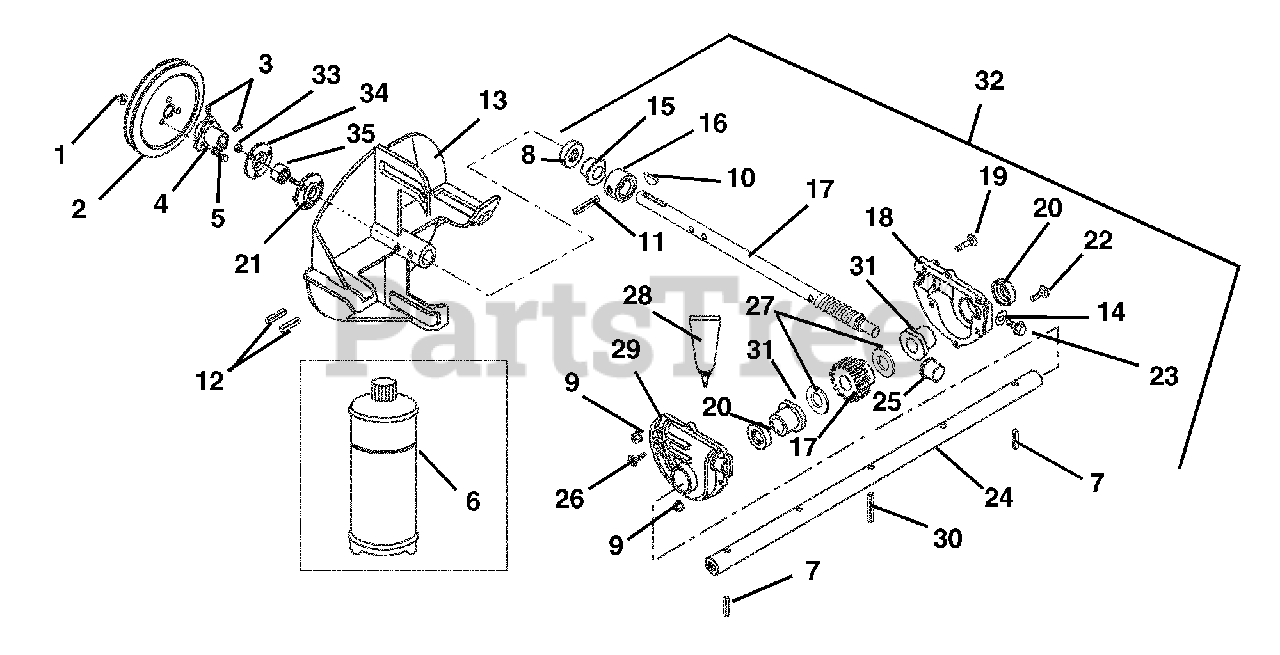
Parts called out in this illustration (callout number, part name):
1	@NUT-SPNLK-FLG .312-18 YWZC
2	PLY-V 8.50 X 1.25 3BLT
3	SCR-SET .31-18X.38 SKHCUPDL
4	HUB ASSEMBLY
5	BLT-SERRDHD SL .31-18X.75 YZ
6	ARIENS 16 OZ.BOTTLE OF L2 LUBE
7	PIN-ROLL .188X1.50
8	SEAL-OIL .750X1.375X.250
9	@NUT-SPNLK-FLG .25-20 YWZC
10	KEY-WDRF .188X.875X.375 SAE11
11	PIN-GRV .188X1.25 TP A
12	PIN-ROLL .250X1.75
13	FAN - 12", BLACK
14	WSHR-FIBER .437X.656X.032
15	BSHG-FLG .750X1.000X.750X1.250
16	THRUST COLLAR
17	SHAFT & WORM GEAR ASSEMBLY
18	CASE, GEAR-LH-LARGE BORE-ALUM.
19	@BLT-RDHDSQNK .25-20X1.25 G5YZ
20	SEAL-OIL 1.000X1.375X.250
21	BEARING FLANGE
22	@BLT-RDHDSQNK .25-20X1.00 G5YZ
23	@SCR-TAP .38-16X.50 HWH TR YWZ
24	SHAFT, RAKE - 24"
25	BSHG-FLG .502X1X.750
26	SCR-TAP 10-24X.75 HWH TR YWZC
27	WSHR-HRD-THRS 1.007X1.542X.062
28	LOCTITE 518 GASKET--6ML TUBE
29	CASE, GEAR-RH-LARGE BORE-ALUM.
30	PIN-GRV .313X1.44 TP C
31	BSHG-FLG 1.00X1.12
32	GEAR CASE - ALUMINUM - 24"
33	@NUT-LK-CTR .25-20 YWZC
34	BEARING FLANGE
35	BRG-BALL .750X1.750X.50
